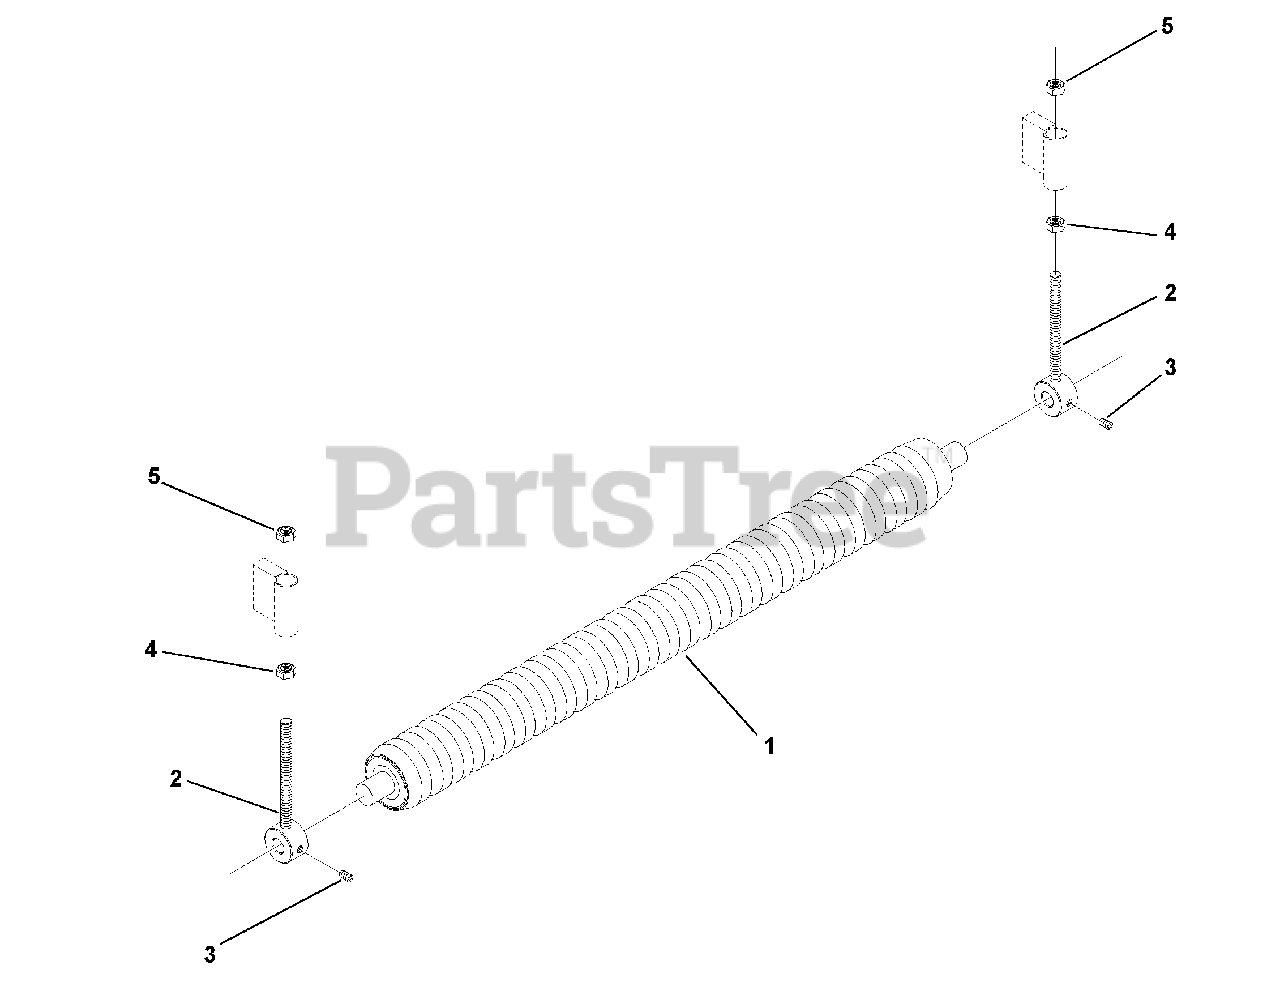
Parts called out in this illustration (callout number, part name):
1	Roller Assembly, Grooved 25-inch (995310)
2	Weldment, Roller Adjustment
3	Set Screw, Square Head .38 x .75
4	Nut, Jam .50-13
5	Nut, Hex .50
